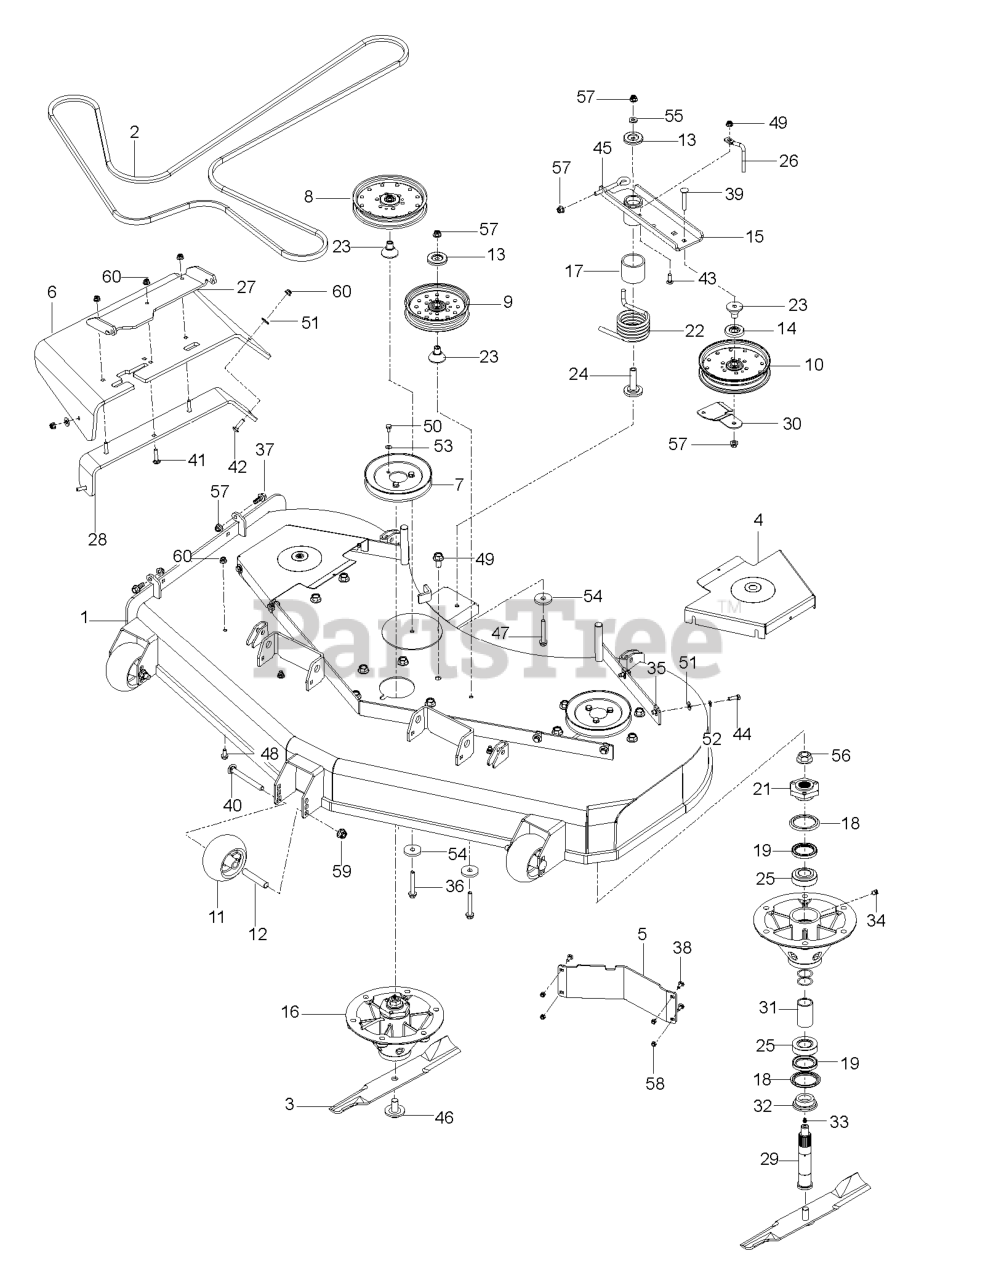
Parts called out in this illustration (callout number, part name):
1	DECK SVC.W/DECALS.PZT.60"
2	BELT 5V 176.00
3	BLADE - HEAVY DUTY 21"
4	SHIELD,BELT, 60" ORANGE
5	BAFFLE, DIVERTER 54"/60" LH
6	CHUTE, DISCHARGE 48-52
7	PULLEY - 5.93 OVER PINS
8	PULLEY - 7" NARROW
9	PULLEY IDLER, 6" NARROW
10	PULLEY - IDLER 7"
11	ROLLER, GAUGE .635 BORN
12	TUBE, ROLLER AXLE
13	DUST SHIELD
14	SHIELD, DUST
15	ASSY, IDLER ARM, PZ
16	SPINDLE.ASSY.ALUMINUM
17	SPACER, IDLER PIVOT
18	SEAL V-RING 55MM
19	SEAL SHAFT
22	SPRING, TORSION, IDLER
23	BEARING, IDLER ARM
24	BEARING, IDLER PIVOT
26	BELT KEEPER
27	BRKT - CHUTE MTG BLACK
28	BRKT, CHUTE SUPPORT BLACK
30	BELT.GUIDE.BLACK
33	ZERK
34	PLUG-VENTED
35	U-CLIP 5/16-18 NUT RETAINER
36	HHFS 3/8-16 X 2-3/4 GR5 ZD
37	HHFS 3/8-16 X 1 GRD 5 ZD
38	1/4-20X3/4 CARR BLT
39	CARRIAGE BOLT 3/8-16 X
40	RHSNB 1/2-13 X 4.75 GR5 ZD
41	BOLT
42	BOLT, CARRIAGE 5/16X1-1/4
44	BOLT.FIN.HEX.5/16-18UNC X 1.00
45	EYE BOLT, 3/8 X 4"
46	BLADE BOLT/WASHER
47	HCS 3/8-16 X 4-1/2 GR 8 ZD
48	HHFS 5/16-18 X 3/4
49	HHFS 1/2-13 X 1 GR5 ZD
50	HCS 5/16-18 X 1/2 GR 5 ZD
51	WASHER.5/16.FLAT.STE.STD.
52	WASH.5/16.SLW.ZD
53	WASH 5/16 DISC SPRING ZD
54	SPINDLE WASHER
55	WASHER, 3/8 THICK
56	NUT FLANGE 3/4-16
57	NUT 3/8-16 HEX FLG NYLOC ZD
58	NUT.1/4-20.HEX.NYLOC.ZD
59	NUT, 1/2-13 HEX FLG NYLOC ZD
60	5/16-18 NYLOC FLANGE NUT
